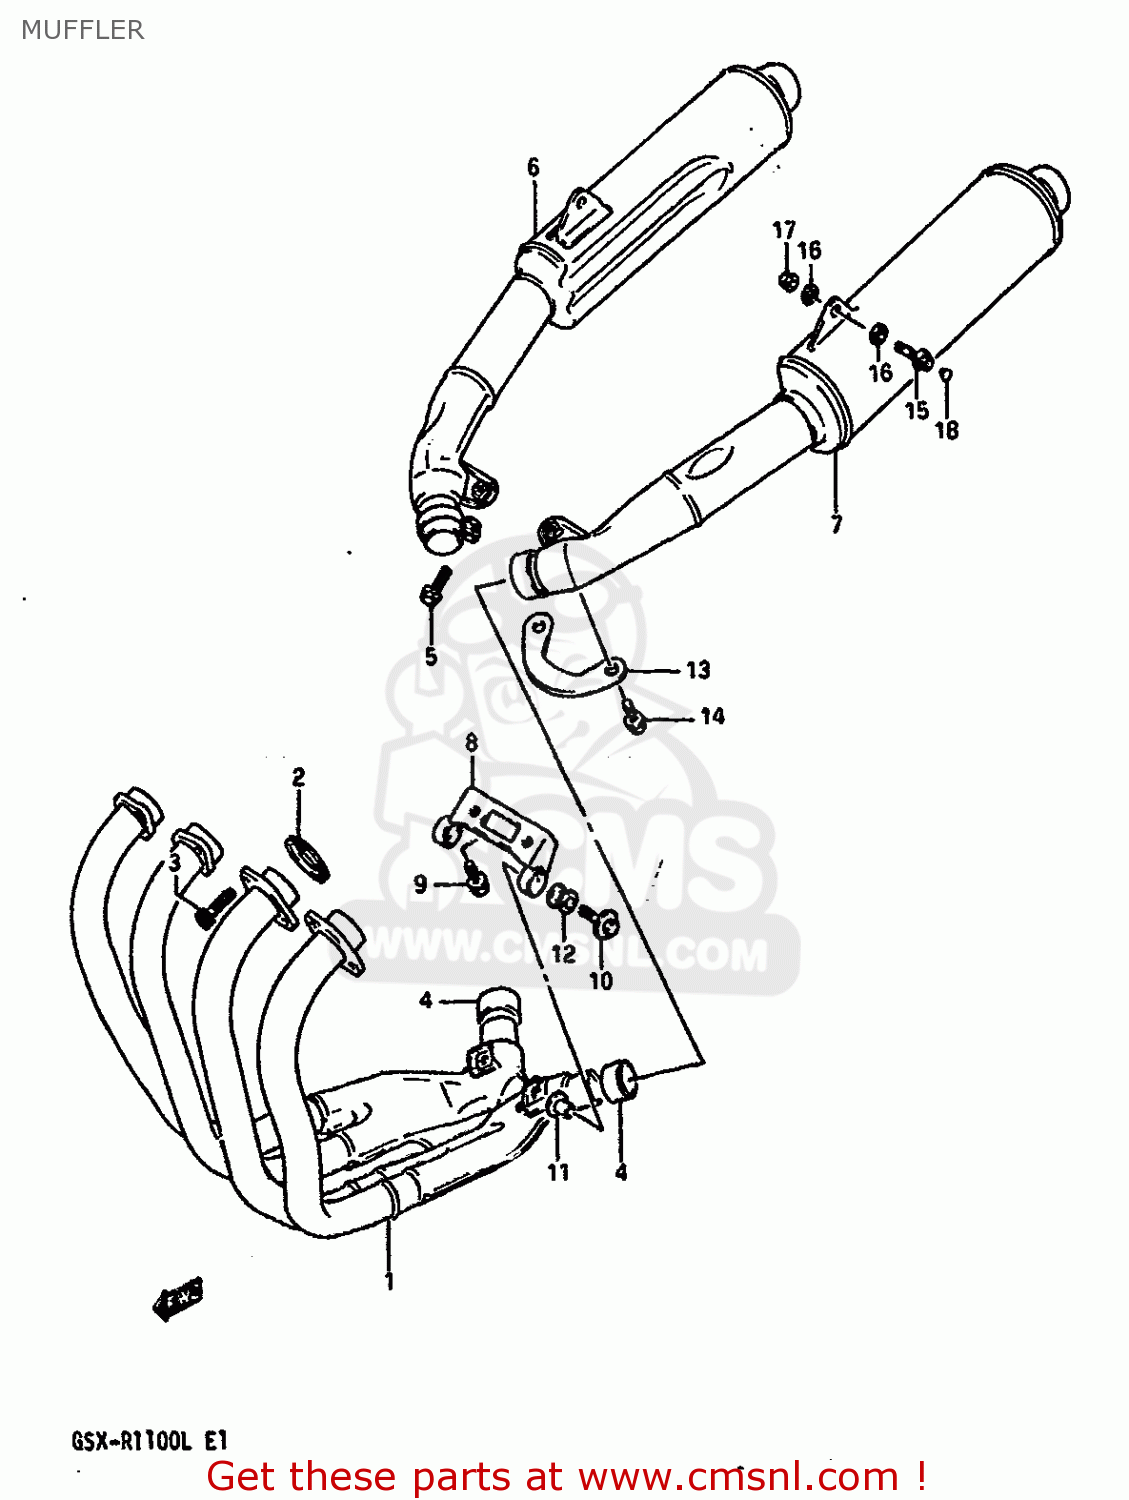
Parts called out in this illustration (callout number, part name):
1	EXHAUST ASSY
2	GASKET,EXHAUST PIPE (NAS)
3	BOLT
4	CONNECTOR,MUFFLER
5	BOLT (8X40)
6	MUFFLER,RH
7	MUFFLER,LH
8	DAMPER,MUFFLER SUPPORT
9	BOLT(8X20)
10	BOLT(8X35)
11	SPACER(8.6X12X18.5)
12	CUSHION
13	PLATE,MUFFLER JOINT
14	BOLT
15	BOLT
16	WASHER (10.5X24X2.3)
17	NUT
18	CAP(OD:12)
